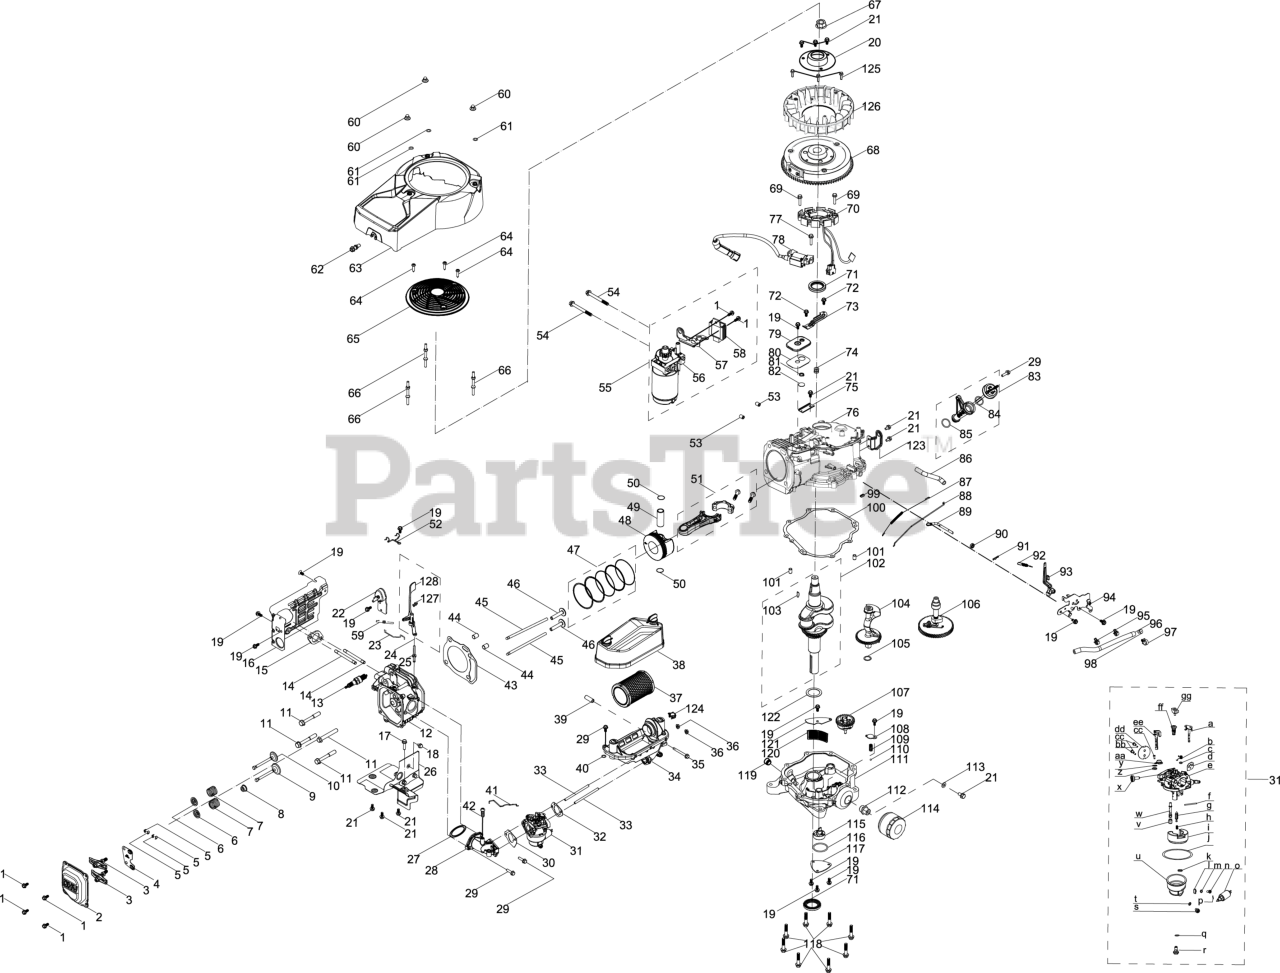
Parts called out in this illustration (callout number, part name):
1	BOLT M6x16
2	VALVE COVER
3	ROCKER ARM ASSEMBLY
4	ROCKER ARM BASE
5	VALVE CAP
6	VALVE SPRING SEAT
7	VALVE SPRING
8	INTAKE VALVE SEAL
9	INTAKE VALVE
10	EXHAUST VALVE
11	BOLT M10x1.25x70
12	CYLINDER HEAD
13	SPARK PLUG (F6RTC/RN11YC/BPR6ES)
14	EXHAUST STUD
15	EXHAUST GASKET
16	ENGINE SHROUD
17	BOLT M6x25
18	BOLT M6x10
19	BOLT M6x14
20	FLYWHEEL HUB COVER
21	BOLT M6x12
22	THERMAL SWITCH
23	THERMAL LEVER
24	AIRVANE CHOKE
25	PIVOT VANE STUD
27	O-RING 36 x 2.5
28	CHOKE LEVER
29	BOLT M6x22
30	INTAKE GASKET
31	CARBURETOR ASSEMBLY HY-7T84JU
32	AIR FLTER GASKET
33	Stud, M6×87
34	AIR FILTER BASE ASSEMBLY
35	BOLT M6x55
37	AIR FILTER W/PREFILTER
38	AIR FILTER COVER ASSEMBLY
39	BUSHING - 11X6X30
40	CARB FUEL DRAIN GASKET
41	CHOKE LEVER
42	SELF TAPPING SCREW 4.8-0.7x16
43	CYLINDER HEAD GASKET
45	PUSH ROD - INDIVIDUAL
47	PISTON RING SET
49	PISTON PIN
50	PISTON PIN SNAP RING
51	CONNECTING ROD ASSEMBLY
54	HEX FLANGE BOLT M8x80
55	Electric Starter
56	ELECTRIC STARTER
59	IDLE SPRING
60	ACORN NUT
64	SELF TAPPING BOLT 5.5x25
65	FLYWHEEL SCREEN
67	FLANGE NUT M20-1.5
69	BOLT M5x28
70	ALTERNATOR
71	OIL SEAL - 35X52X7
72	HEX FLANGE BOLT M5x10
73	WIRE PLATE
75	BREATHER SCREEN
77	BOLT M6x28
78	IGNITION COIL
79	BREATHER COVER
80	BREATHER COVER GASKET
81	BREATHER VALVE SPRING
82	Breather Valve
83	DIPSTICK ASSEMBLY
86	BREATHER HOSE
87	THROTTLE DAMPENING SPRING
88	THROTTLE LINKAGE
89	GOVERNOR GEAR SHAFT
90	GOVERNOR SEAL
91	COTTER PIN
92	GOVERNOR SPRING
93	GOVERNOR ARM ASSEMBLY
94	CONTROL BRACKET ASSEMBLY
95	CARBURETOR HOSE CLAMP
96	FUEL HOSE 6.3x12.5x270
97	FUEL LINE SUPPORT CLAMP
100	CRANKCASE GASKET
101	DOWEL PIN 9 X 14
102	CRANKSHAFT ASSEMBLY
103	WOODRUFF KEY
104	BALANCE SHAFT ASSEMBLY
105	WASHER 17.2 x 26 x 1
106	CAMSHAFT ASSEMBLY
107	GOVERNOR GEAR
108	PRESSURE RELEASE COVER
109	PRESSURE RELEASE SPRING
110	OIL PUMP STEEL BALL
111	CRANKCASE COVER
112	OIL FILTER ADAPTER
113	WASHER - 6.2X1.5X13
114	ENGINE OIL FILTER
115	OIL PUMP ASSEMBLY
117	OIL SEPARATOR
118	BOLT M8 x 40
120	FILTER SCREEN
121	OIL SCREEN PLATE
122	WASHER - 35.4X1X52
125	Bolt, M5×18
126	COOLING FAN
127	Choke Lever Rack
128	Shield
